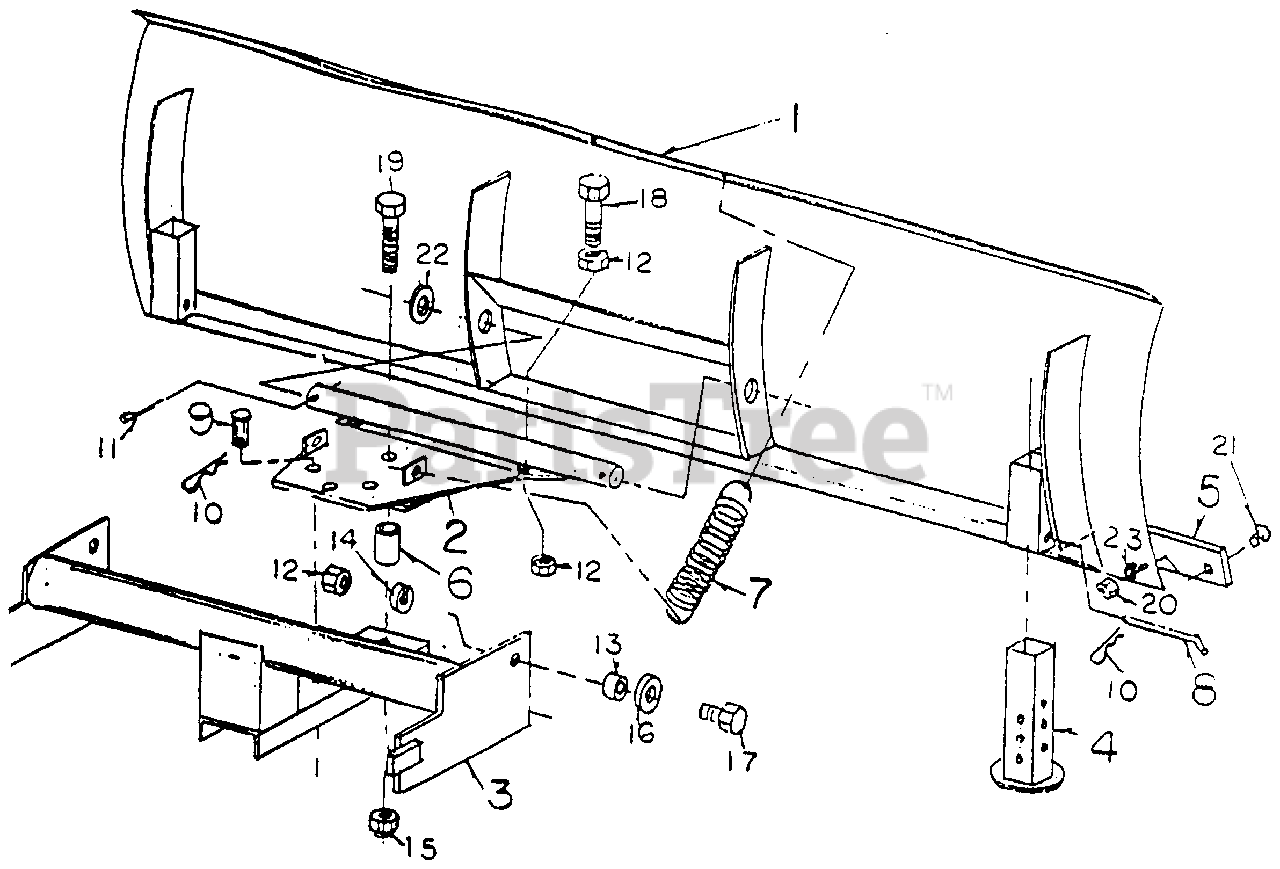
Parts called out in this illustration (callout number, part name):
1	54" Blade
3	54" Blade Mount
4	Skid Plate
5	Replaceable Blade
11	3/16 Cotter Pin
12	1/2-13 Nut
13	Bushing
14	1/2-Lock Washer
15	1/2 Lock Nut
16	1/2 Flat Washer
17	1/2-13 x 1-1/2
18	1/2-13 x 2-1/4
19	1/2-13 x 3
20	5/16-18 Nut
21	5/16-18 x 1 Carg.
23	5/16 Lock Washer
